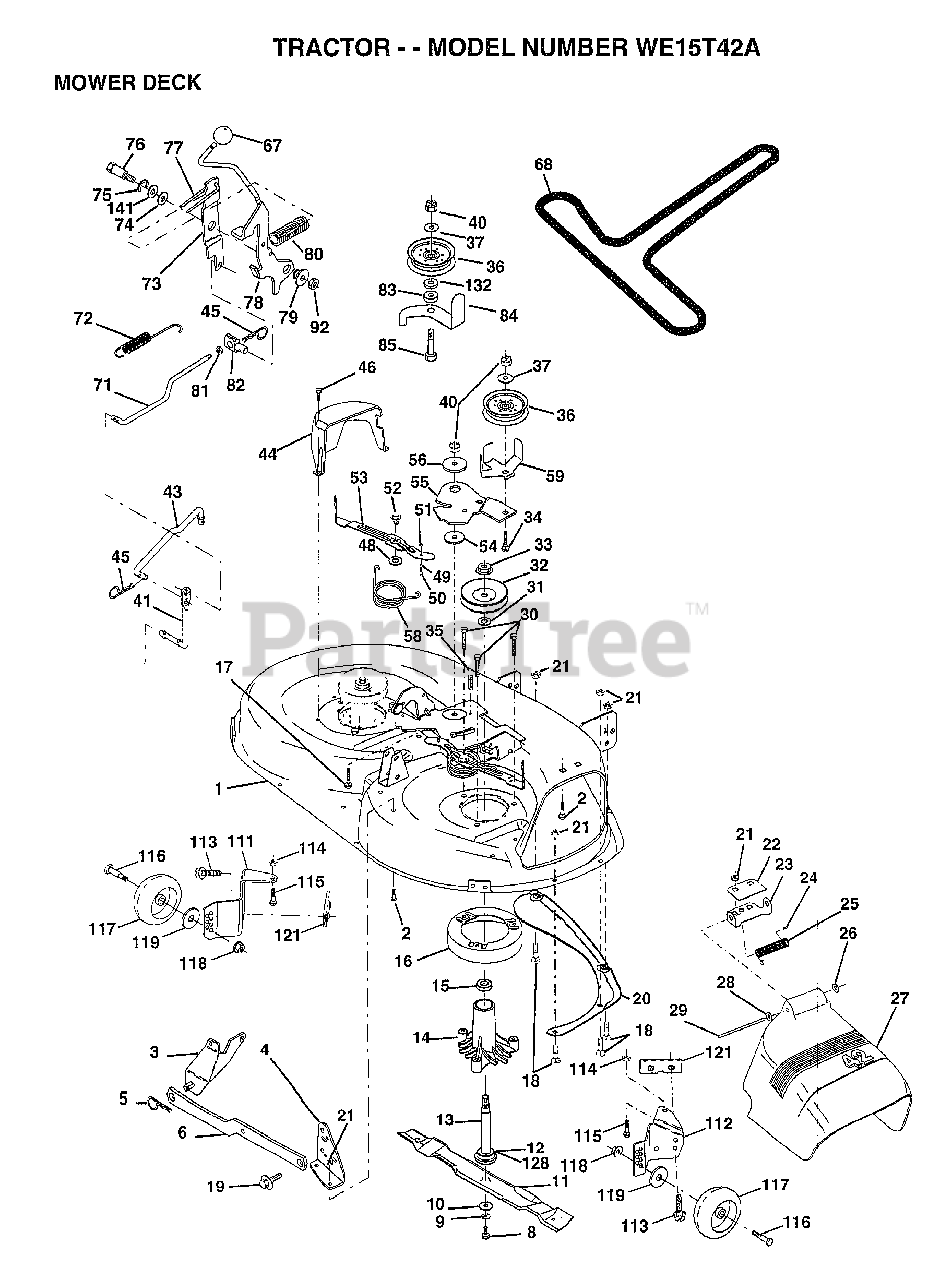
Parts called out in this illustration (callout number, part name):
1	"HOUSING ASSY.42"""
2	BOLT
3	BRKT ASM SWAY BAR
4	BRKT DECK SW BAR
8	BLADE BOLT
10	WASHER.HARD.BLADE
11	"BLADE.42"" HIPERF"
12	BEARING.BALL
14	HSG ASM MANDREL
15	BEARING
16	STRIPPER RND MWR
17	BOLT RDHD 3/8-16
18	BOLT
19	BOLT SHD 5/16-18
20	BAFFLE VORTEX 42
22	STIFFENER BRKT
23	DEFLECTOR BRKT
24	CAP-SLEEVE LT
25	SPRING TORSION
26	NUT PUSH M
27	DEFLECTOR.SHIELD
28	WASHER
29	HINGE ROD
30	"SCREW-THD ROLL,WA"
31	WASHER
32	PULLEY.MANDREL.42
34	BOLT
35	XMAS TREE FASTNER
36	FLAT IDLER PULLEY
37	WASHER
41	PIVOT ROD
43	ROD CLUTCH W/NIBS
44	GUARD MAND LH BLK
45	RETAINER M
46	SCREW.1/4-20X5/8
48	HARD SMALL WASHER
49	ROLLER ASM-CAM
50	SHOULDER BOLT
51	LOCKNUT
52	BOLT.SHLD.5/16-18
53	BRAKE PAD ARM ASM
54	HARDENED WASHER
55	ARM-IDLER
56	SPACER RETAINER
58	SPRING TORSN BRAK
59	GUARD IDLER TUV
67	KNOB.RD.7/16-14
68	BELT.V.T-PATH
71	ROD CLUTCH 38/42
72	RETURN SPRING
73	CLUTCH ARM SECOND
74	WASHER
75	RING
76	SHOULDER BOLT
77	SPRING KEEPER
78	LEVER.ASM.CLUTCH
79	BUSHING
80	SPRING.CLUTCH.MWR
81	NUT
82	TRUNION ADJ
83	WASHER
84	"KEEPER-BELT,FIXED"
85	BOLT
92	NUT
111	BRACKET.GWHL.LH.
112	BRACKET.GWHL.RH.
113	SCREW
116	BOLT M
117	WHEEL.GUAGE
118	LOCKNUT
119	WASHER
121	BRACKET.EXTRD.GWL
128	WASHER.FELT.
132	WASHER GT
141	WASHER .T
